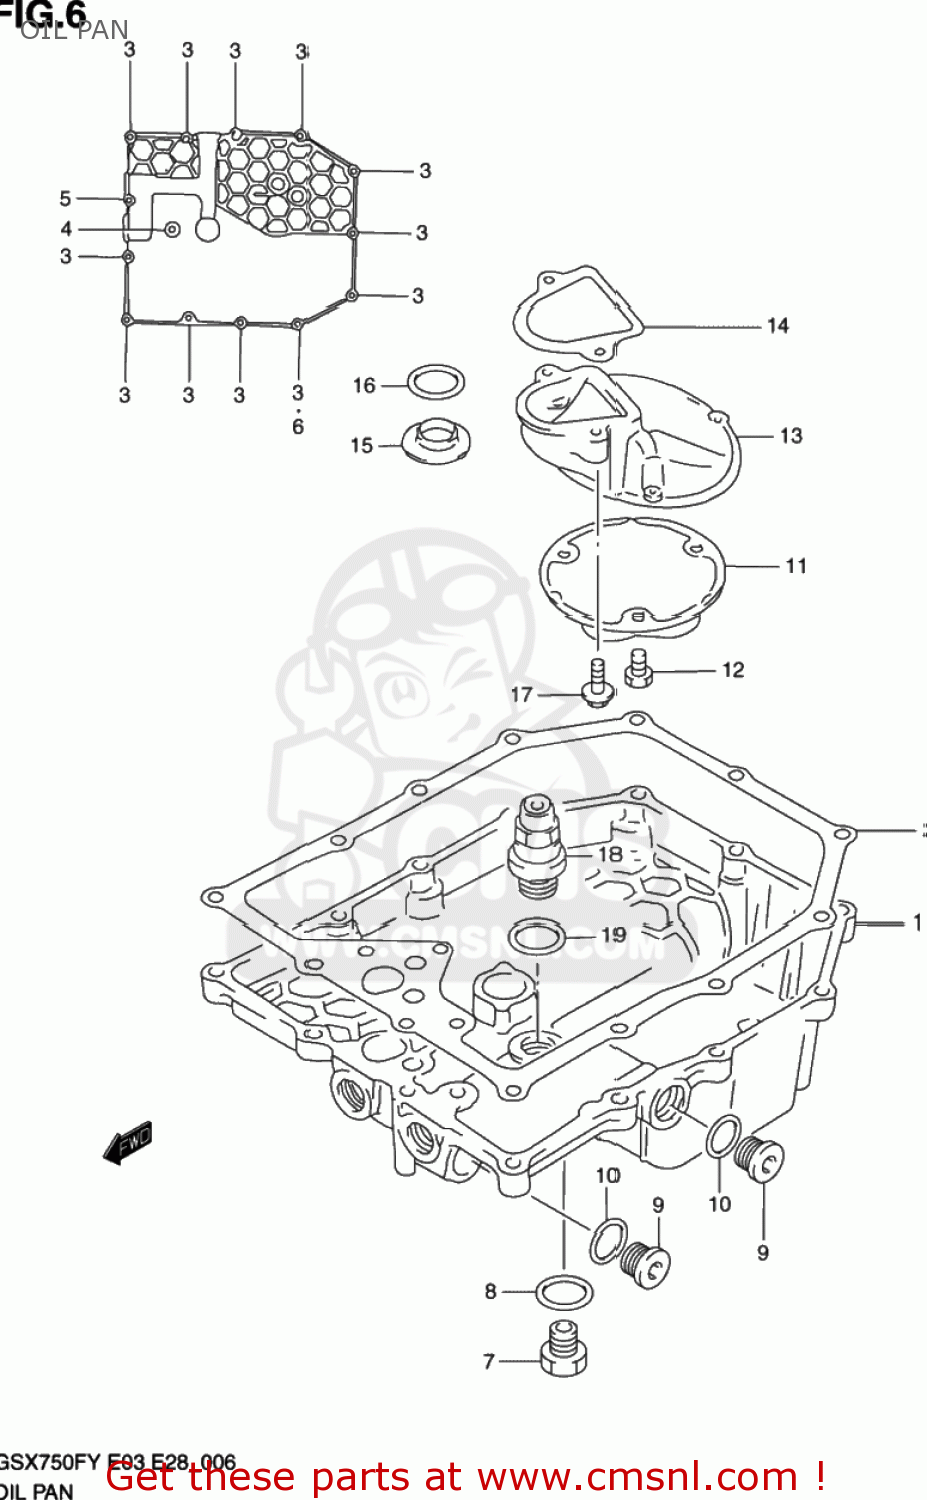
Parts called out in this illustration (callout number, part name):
1	PAN,OIL
2	GASKET,OIL PAN(ASB) (NAS)
3	BOLT
4	BOLT
5	BOLT
6	GASKET(5.8X11X1.2) (NAS)
7	PLUG
8	GASKET(13.8X18.8X4.8) (NAS)
9	PLUG,16X8
10	GASKET(16X22X2) (NAS)
11	STRAINER,ENGINE OIL
12	BOLT
13	PROTECTOR,OIL STRAINER
14	GASKET,OIL STRAINER PROTECTOR (NAS)
15	GASKET,OIL OUTLET (NAS)
16	O RING(D:3.2,ID:17.8)
17	BOLT
18	VALVE ASSEMBLY,OIL RELIEF
19	GASKET(16X22X2) (NAS)
